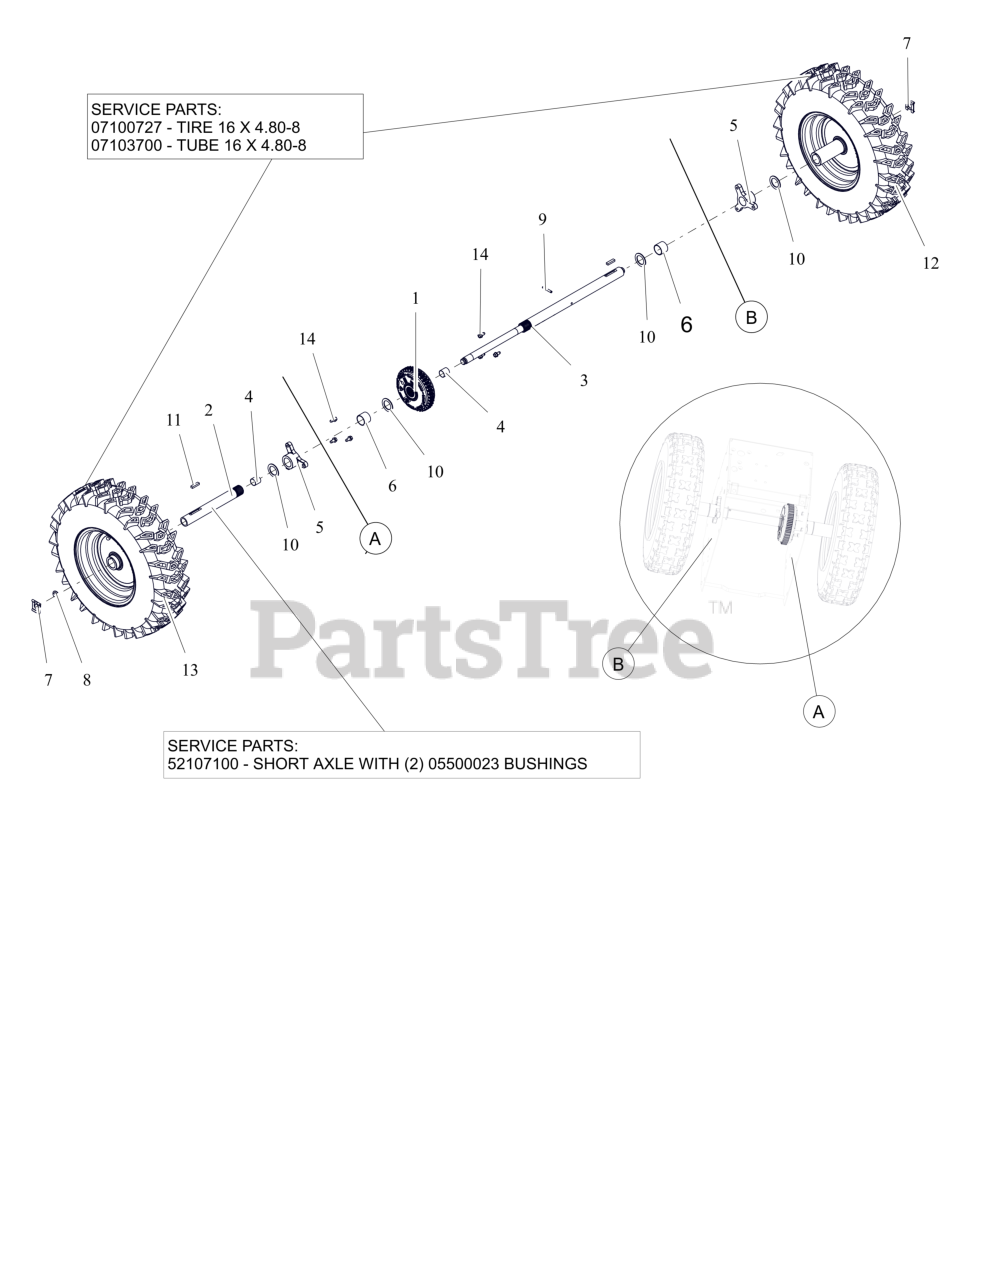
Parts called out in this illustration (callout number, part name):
1	DIFFERENTIAL, AUTOMATIC
2	KIT, SHORT AXLE W/BUSHINGS
3	AXLE, LONG - DIFFERENTIAL
4	BSHG-SLV .706X.764X.75 BRZ
5	BUSHING, AXLE
6	BSHG-SLV, 1.012X1.125X.875
7	CLIP, SNAP .625 DIA
8	RG-RTNG-EXT .625X.042
9	PIN-ROLL .188X1.25
10	WSHR, FLT 1.010X1.505X.062 ZCC
11	KEY-RECT .25X.188X1.00
12	TIRE/WHEEL LH 16X4.8-8 DIFF T2
12	TIRE, 4.80-8 K478
13	TIRE/WHEEL RH 16X4.8-8 DIFF T2
13	TIRE, 4.80-8 K478
14	SCR-TAP .25-20X.50 HWH ZCC
